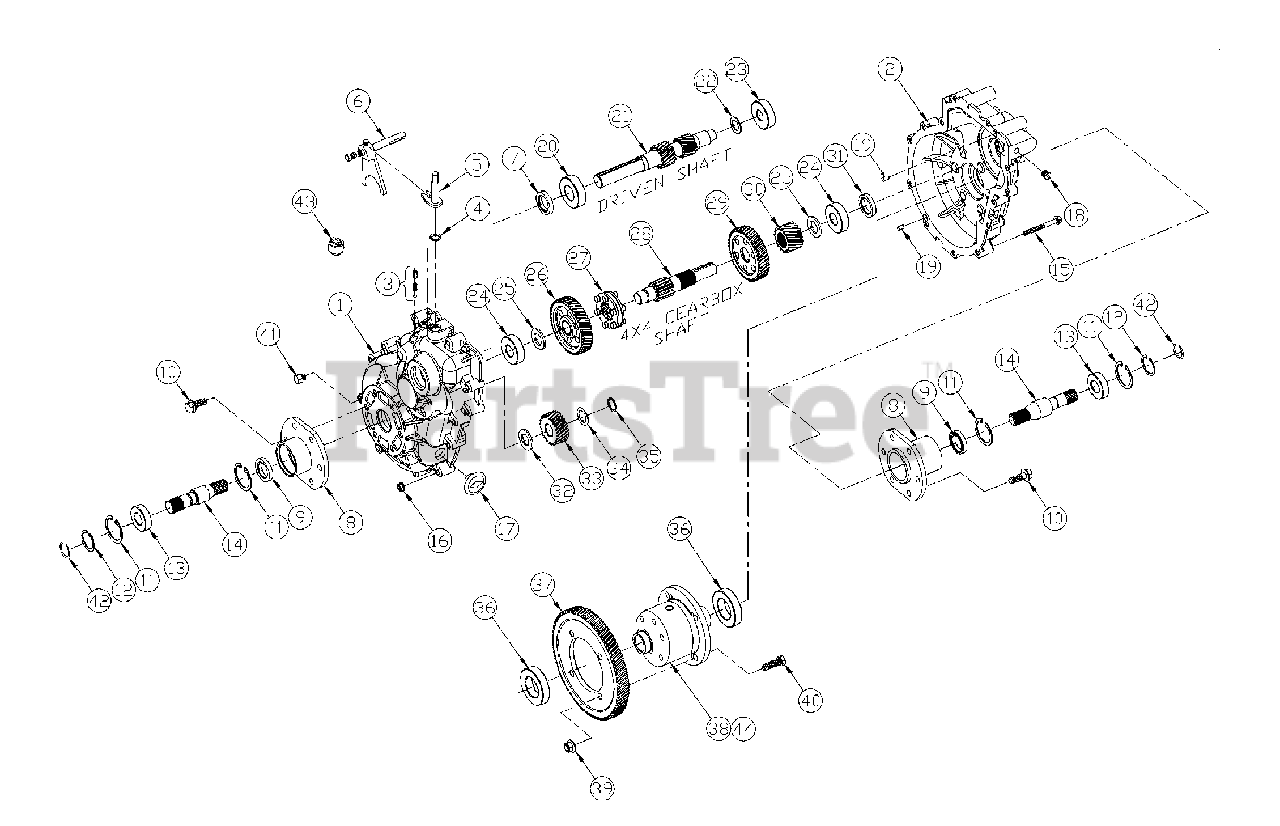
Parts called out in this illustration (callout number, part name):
1	DANA HOUSING AND SHAFT ASSBLY
2	DANA HOUSING-AXLE FIN
3	DANA KIT, DETENT
4	DANA SEAL - OIL
5	DANA ACTUATOR ASSY
6	DANA SHIFT ROD SUB-ASSY
7	DANA SEAL - OIL
8	REAR TUBE ASSY
9	SEAL - OIL
10	DANA SCREW - FLG HEAD
11	DANA RING, RETAINING
12	RING - RETAINER
13	BEARING - BALL SINGLE
14	SHAFT - AXLE, FIN
15	DANA SCREW - FLG HEAD
16	DANA NUT - LOCK
17	DANA PLUG - RUBBER
18	DANA VENT PLUG
19	DANA PIN - DOWEL
20	DANA BEARING 6205
21	DANA SHAFT - INPUT FIN
22	DANA KIT, SHIM
23	DANA BEARING -6303 BALL SINGLE
24	DANA BEARING -6204 BALL SINGLE
25	DANA SPACER - FLAT
26	DANA GEAR ASSY - FORWARD
27	DANA GEAR - CLUTCH
28	DANA SHAFT - INTERMEDIATE FIN
29	DANA GEAR ASSY - REVERSE
30	DANA GEAR - HELICAL FIN
31	DANA SEAL - OIL
32	DANA WASHER - THRUST
33	DANA GEAR ASSY - IDLER
34	DANA WASHER - THRUST
35	DANA RING - SNAP
36	DANA BEARING 6007
37	DANA GEAR - HELICAL FIN
38	DIFFERENTIAL, AUTO-LOCK
39	RPBY 35704
40	DANA BOLT - HEX
41	DANA DRAIN PLUG
42	RETAINER - SHAFT, AXLE
43	SWITCH, NEUTRAL, DANA GBOX
44	AUTO-LOK KIT
